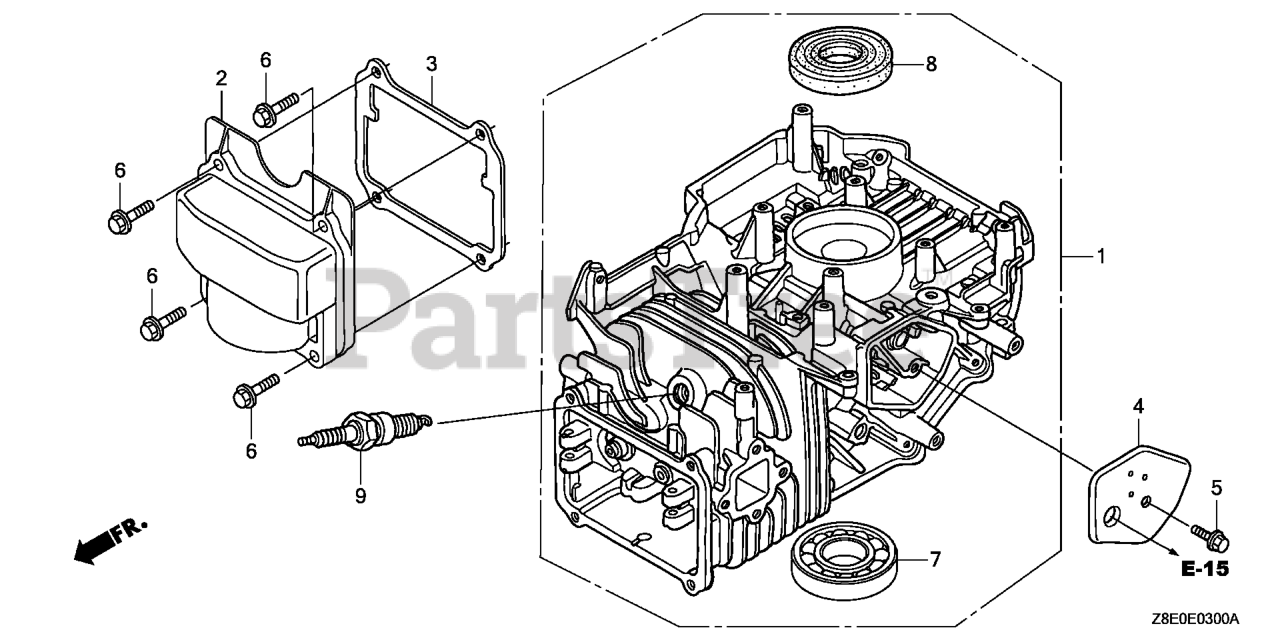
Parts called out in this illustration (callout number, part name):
1	CYLINDER ASSY.
2	COVER, CYLINDER HEAD
2	COVER, HEAD
3	GASKET, HEAD COVER
4	COVER, BREATHER (Honda Code 5580006). (BREATHER VALVE ASSY.)
5	BOLT, FLANGE (6X14)
6	BOLT, FLANGE (6X12) (CT200)
6	BOLT, FLANGE (6X25) Use up to Engine SN 2056819.
7	BEARING, RADIAL BALL
8	OIL SEAL (25.4X74X6)
9	SPARK PLUG (BPR5ES) (NGK)
9	SPARK PLUG (BPR6ES) (NGK)
